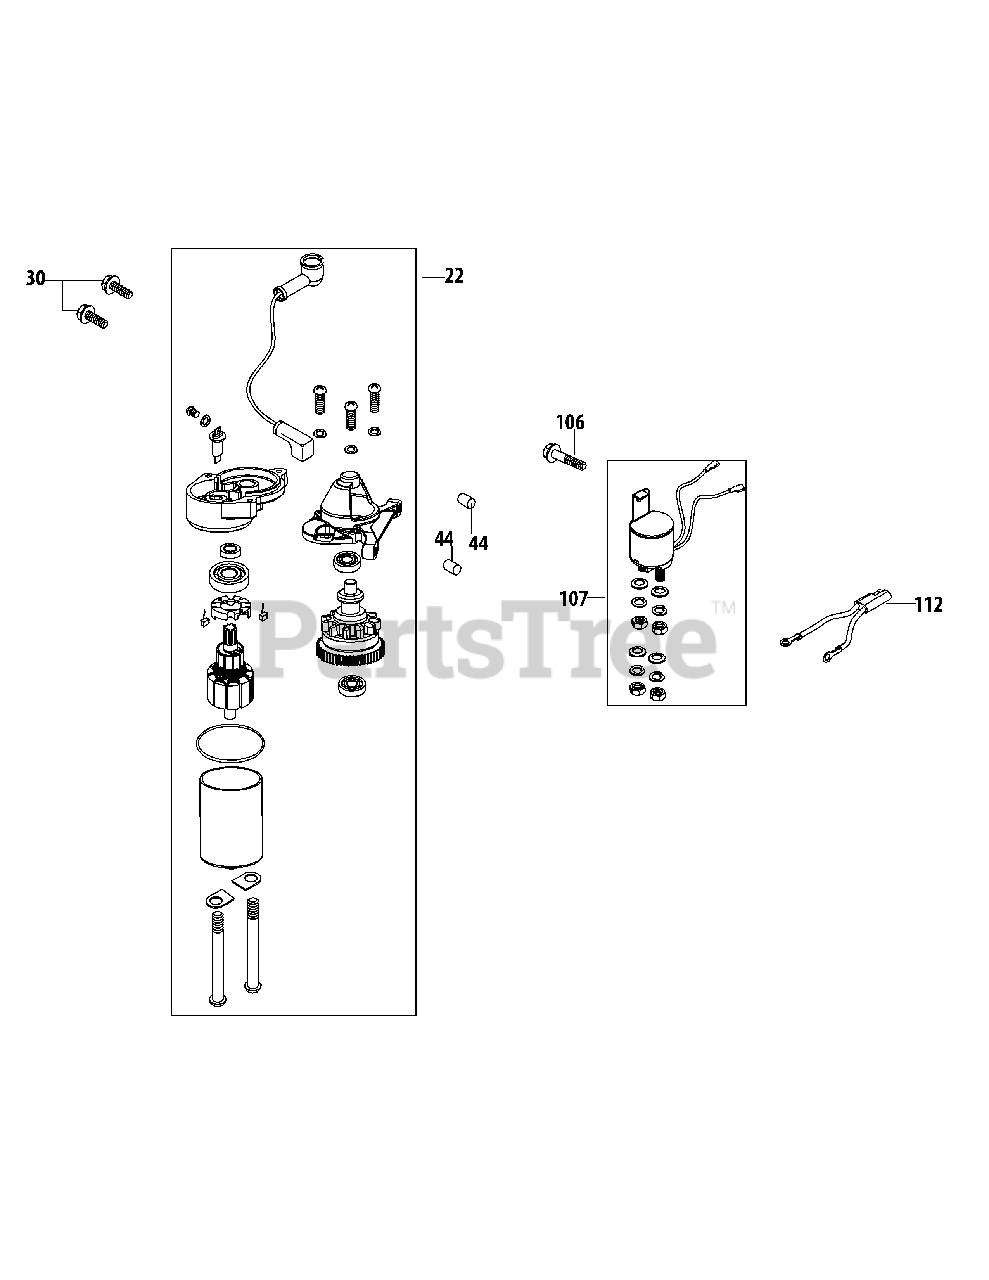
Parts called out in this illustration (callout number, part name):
22	Electric Starter Assembly
30	Bolt M6X30
44	Starter Housing Dowel 8X8
106	Bolt M6X35
107	Starter Relay Assembly
112	Power Connector Harness
